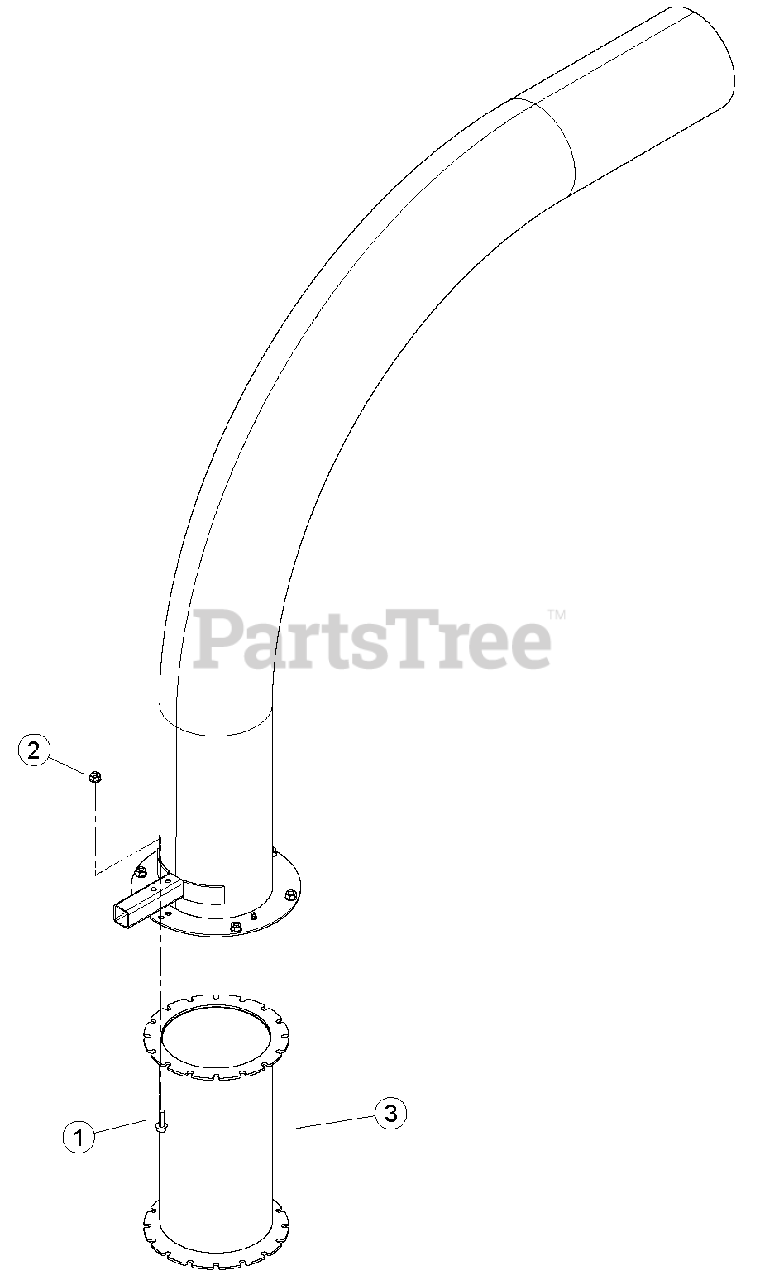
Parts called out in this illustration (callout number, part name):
1	BOLT, 3/8 X 1-1/4 FLANGE NC
2	NUT, 3/8-16 NYLOCK FLANGE
3	WELDMENT, CHUTE EXTENSION
